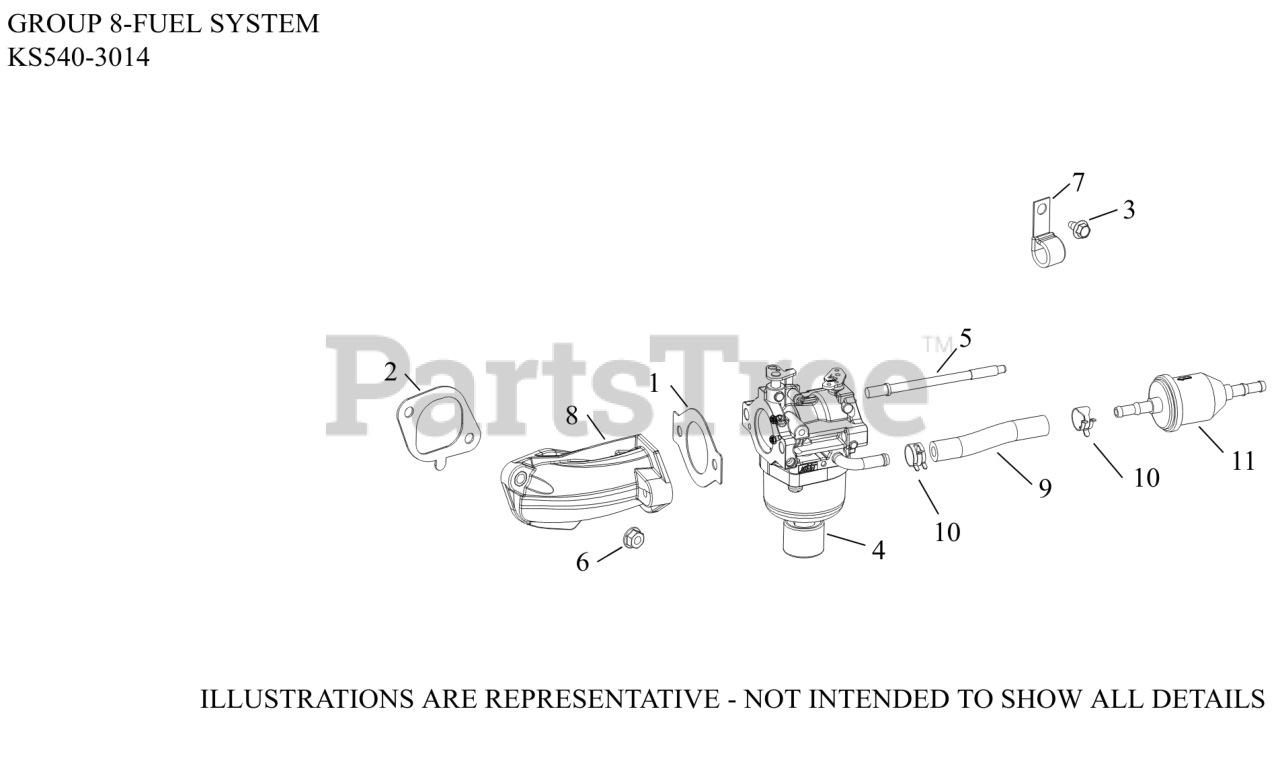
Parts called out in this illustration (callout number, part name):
1	GASKET, CARBURETOR (THROTTLE)
2	GASKET, INTAKE MANIFOLD
3	SCREW, THREAD FORMING
4	KIT,CARB(NIKKI)
5	STUD, CARBURETOR
6	NUT, FLG M6X1.0
7	CLIP, CABLE
8	MANIFOLD, INTAKE ASSEMBLY
9	HOSE,LW PERM.FUEL 24.00"-USE 25 111 81-S
10	SPRING CLAMP, HOSE
11	FILTER,FUEL 75 MICRON (GRAVTY FEED)
NI	HIGH ALTITUDE KIT (5000 FT)
NI	KIT, OVERHAUL
NI	KIT, CHOKE SHAFT
NI	KIT, O-RING
NI	KIT, SOLENOID (NIKKI)
NI	KIT, BOWL WITH O-RINGS
NI	KIT, FLOAT AND INLET NEEDLE FOR GRAVITY
NI	KIT, THROTTLE SHAFT
